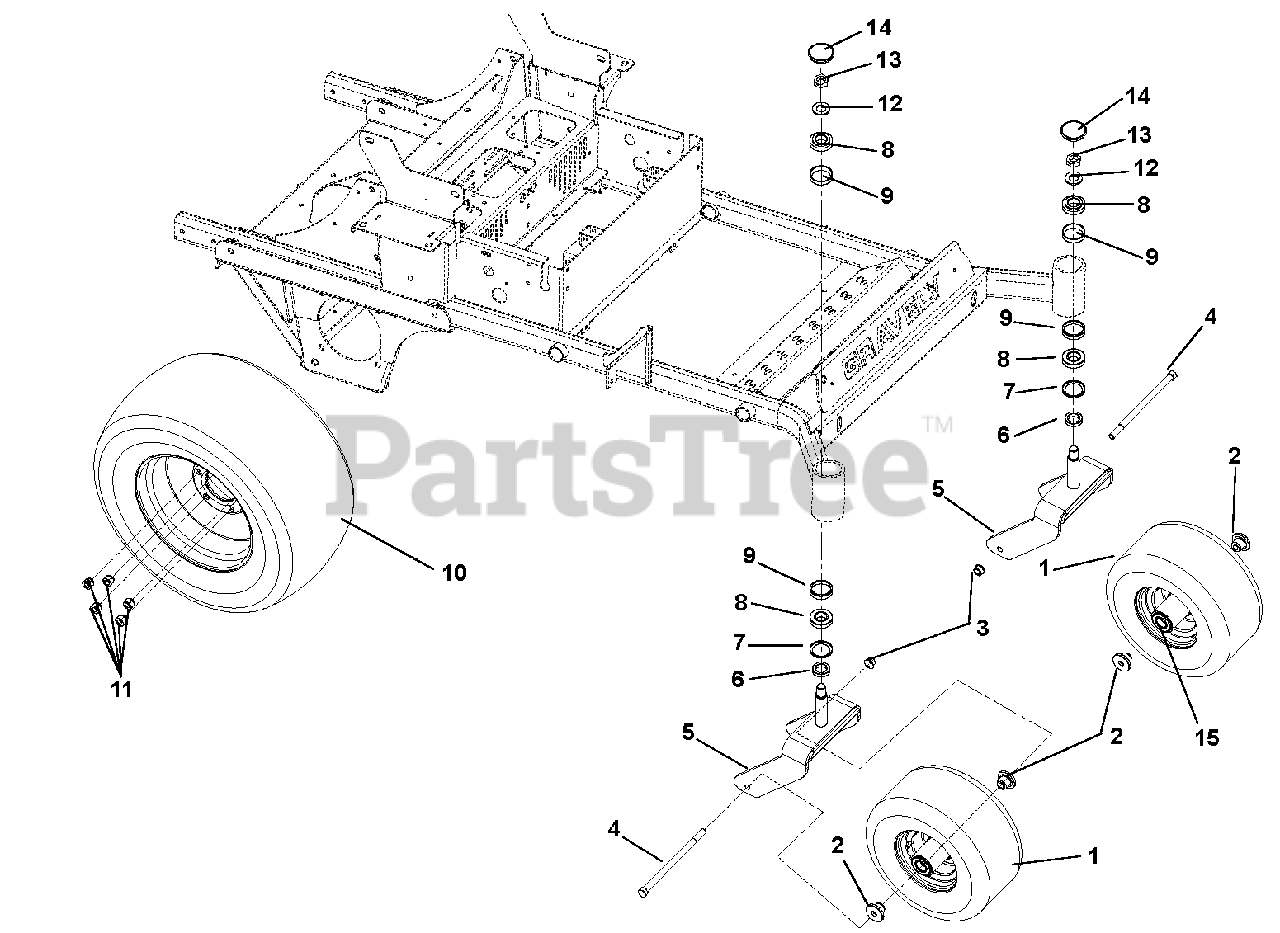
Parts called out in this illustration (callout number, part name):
1	Tire/Wheel Assembly, 15 x 6.00-6 Smooth
2	Spacer, Front Wheel
3	Nut, .Nyloc Flange 50-13
4	Bolt, Hex .50-13 x 9.00 Grade 5
5	Caster Fork Weldment
6	Spacer 1.258 x 1.75 x .550
7	Seal, Oil 1.75 x 2.332 x .312
8	Bearing, Cone 1.25 x .66
9	Bearing, Cup 2.328 x .465
10	Tire/Wheel Assembly, 24 x 11.50-12 (992201, 203, 204, 198)
11	Nut, Wheel .50-20 13/16 Across Flats Automotive Type
12	Washer, Flat Steel .812 x 2.00 x .148
13	Nut, Jam Center Lock .75-16
14	Cap, Dust
15	Bearing, 25 mm ID x 52 mm OD x 15 mm
